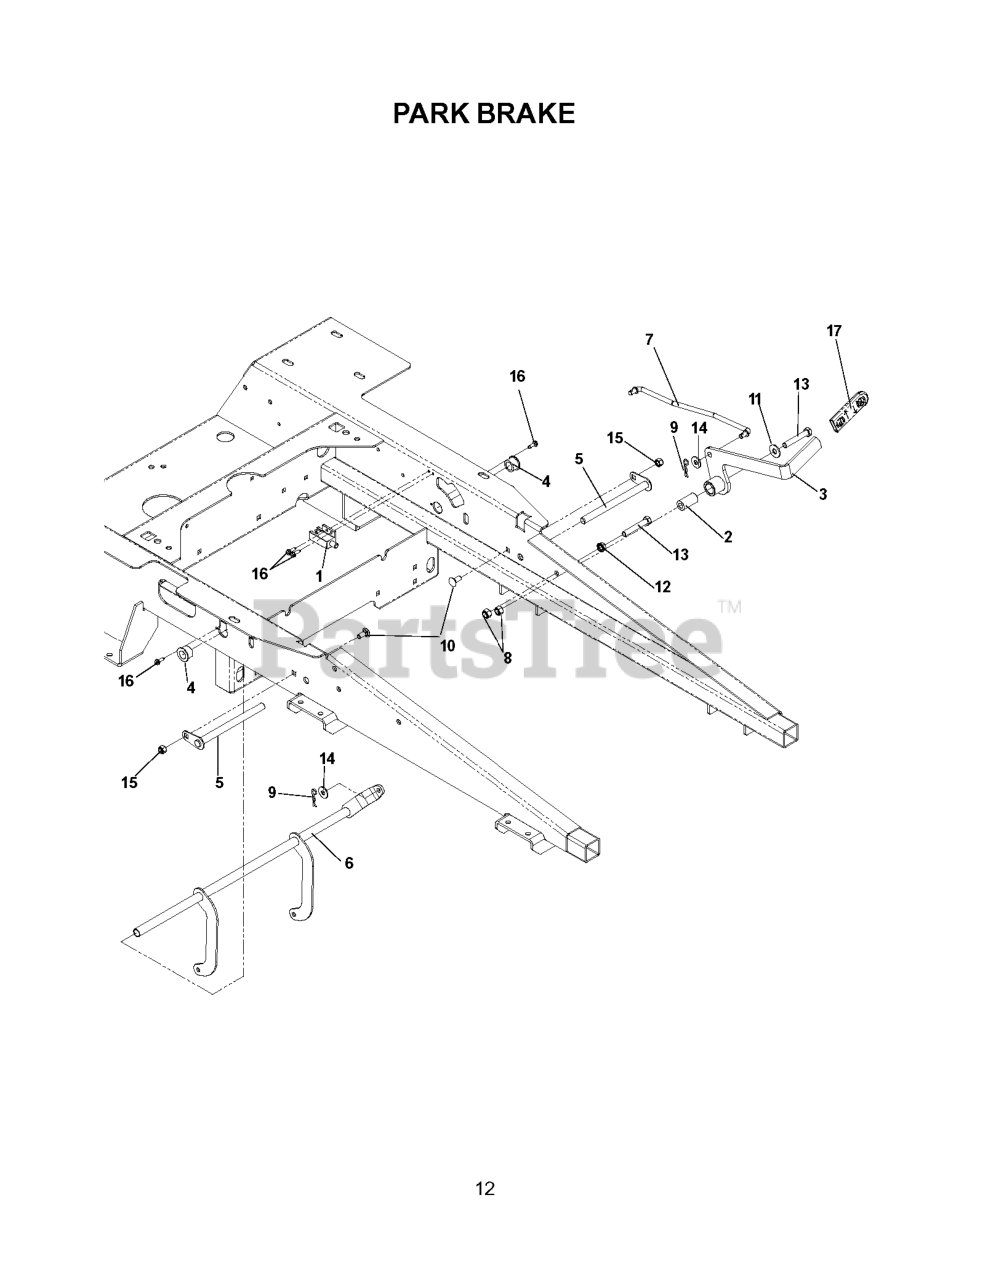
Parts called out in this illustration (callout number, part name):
1	SWITCH, INTERLOCK
2	BUSHING, SLEEVE
3	BRAKE LEVER WLDMT
4	PLASTIC BUSHING
5	PIVOT SHAFT
6	BRAKE SHAFT
7	BRAKE LINKAGE
8	NUT 3/8-16 NYLOC
9	HAIRPIN #2
10	BOLT 5/16C X 3/4" CARRIAGE
11	WASHER 3/8 FLAT
12	NUT 5/16C WHIZ
13	HCS 3/8C X 2 1/4
14	WASHER 5/16 FLAT
15	NUT 5/16 NYLOC
16	SCREW #10 X 1/2 SELF TAPPING
17	GRIP, PARK BRAKE
